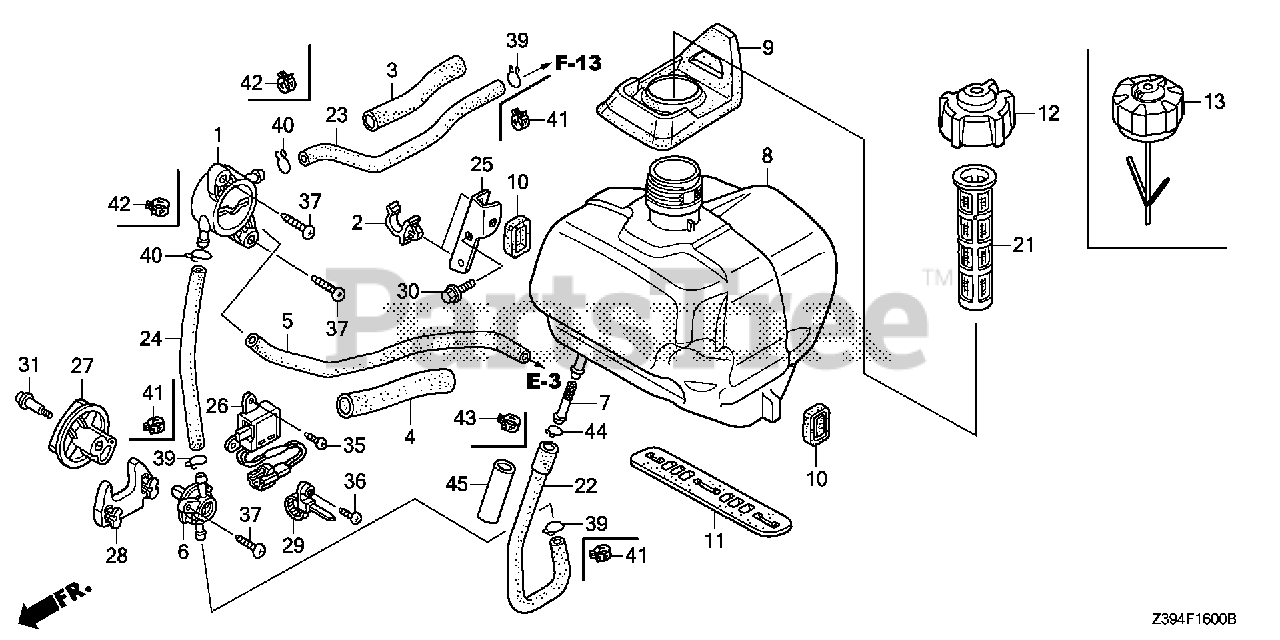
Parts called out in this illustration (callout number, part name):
1	PUMP ASSY., FUEL (MSDS)
2	CLIP, TUBE
3	RUBBER A, SUPPORTER
4	RUBBER B, SUPPORTER
5	TUBE, DIAPHRAGM
6	PETCOCK ASSY.
7	FILTER, FUEL
8	TANK, FUEL (COO)(FOR U.S.A.)
8	TANK, FUEL
8	STARTER ASSY., RECOIL (FOR U.S.A.)
8	STARTER ASSY., RECOIL
9	SEAL, FUEL FILLER NECK
10	RUBBER A, TANK MOUNTING
13	CAP ASSY., FUEL TANK
21	FILTER, FUEL
22	TUBE, FUEL TANK (FKM)
23	TUBE A, FUEL (FKM)
24	TUBE B, FUEL (FKM)
25	BRACKET, FUEL TUBE
26	SWITCH ASSY., ENGINE STOP
27	KNOB, ENGINE SWITCH
28	PLATE, ENGINE SWITCH
29	BAND, HARNESS
30	BOLT, FLANGE (6X12) (CT200)
31	SCREW, PAN (4X19)
35	SCREW, TAPPING (3X12)
36	SCREW, TAPPING (3X16)
37	SCREW, TAPPING (5X20) (PO)
41	CLAMP, TUBE (D8)
42	CLAMP, TUBE (D8.5)
43	CLAMP, TUBE (D10.5)
45	RUBBER, SUPPORTER (C)
